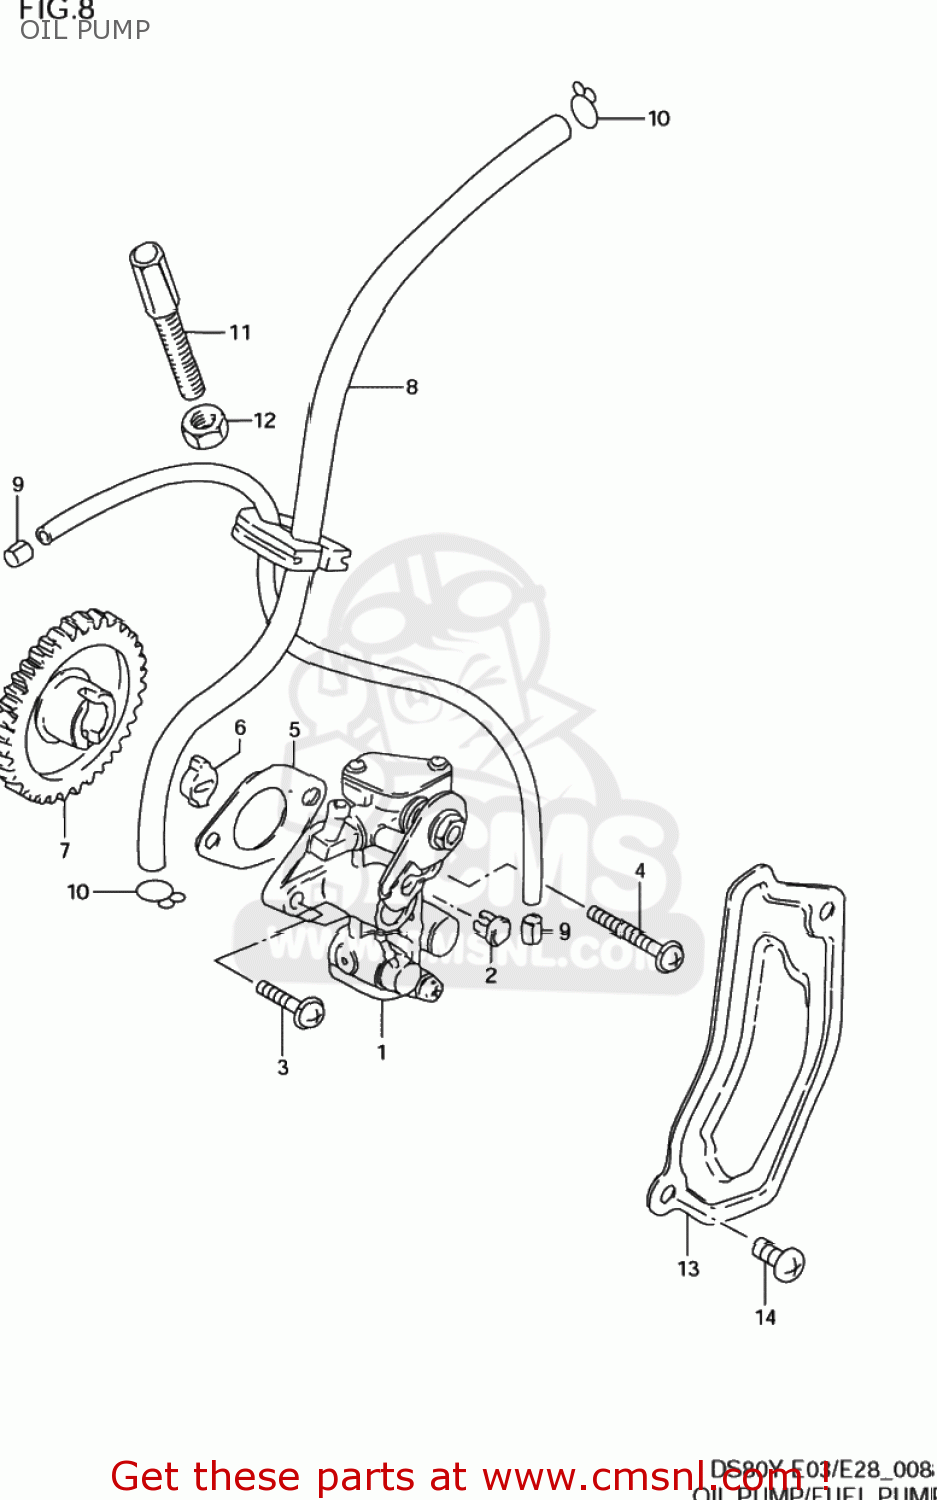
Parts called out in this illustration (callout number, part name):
1	PUMP ASSY,OIL
2	TERMINAL,CABLE
3	SCREW
4	SCREW
5	GASKET,OIL PUMP (NAS)
6	PIECE,OIL PUMP DRIVE
7	GEAR,OIL PUMP DRIVE
8	HOSE,OIL NO.2
9	CLIP
10	CLIP
11	BOLT
12	NUT
13	CAP,OIL PUMP INSPECTION
14	SCREW
